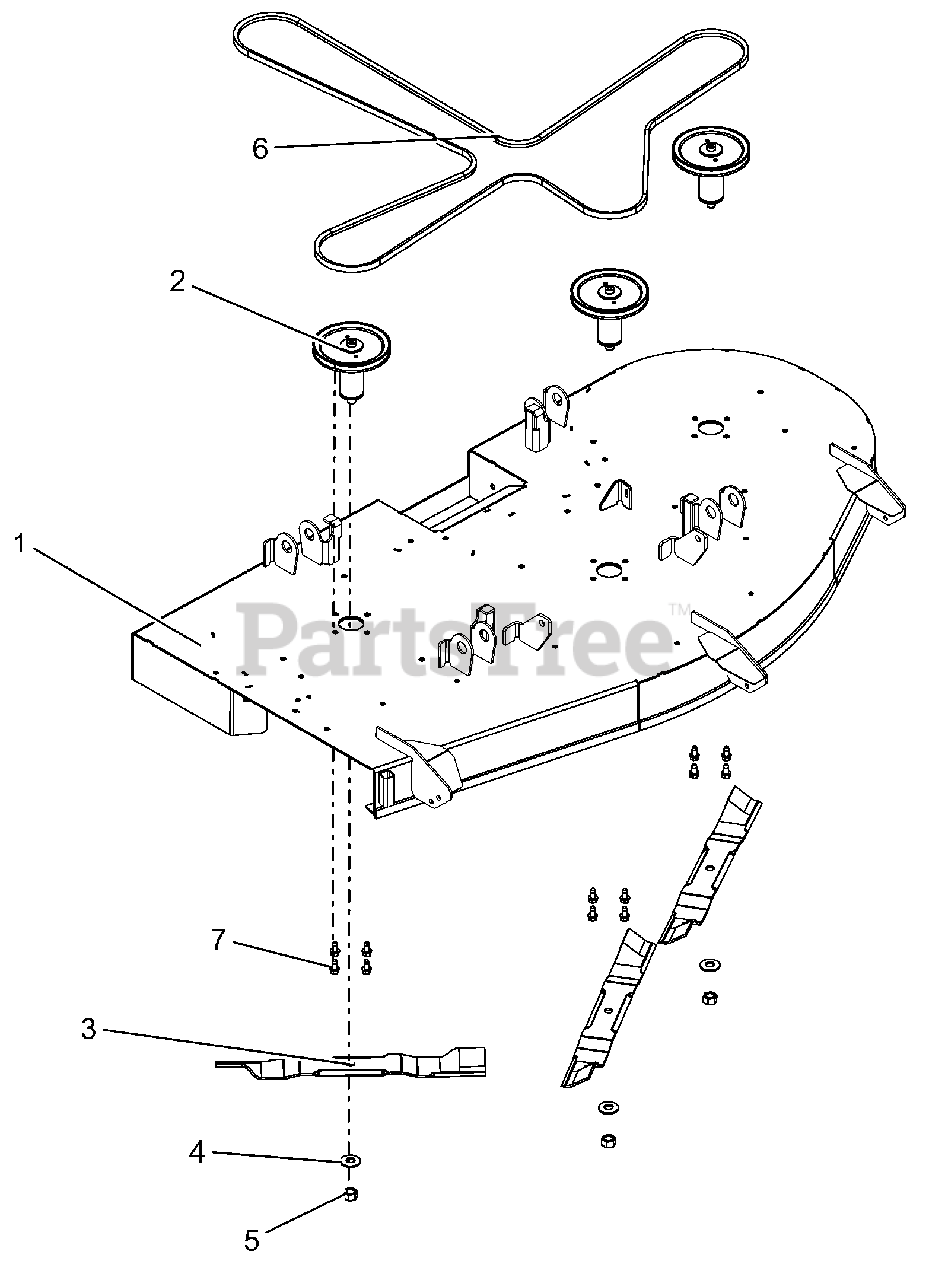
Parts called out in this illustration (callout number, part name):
1	KIT, 60" GRAVELY DECK W/DECALS
2	KIT, DECK SPINDLE ASM-60
3	BLADE, 21" 35 DEG
4	WSHR-BLVL .669X1.535X.138
5	NUT-HEX .62-18 YWZC
6	BELT, HA
7	@SCR-TAP .38-16X.75 HWH TR YWZ
